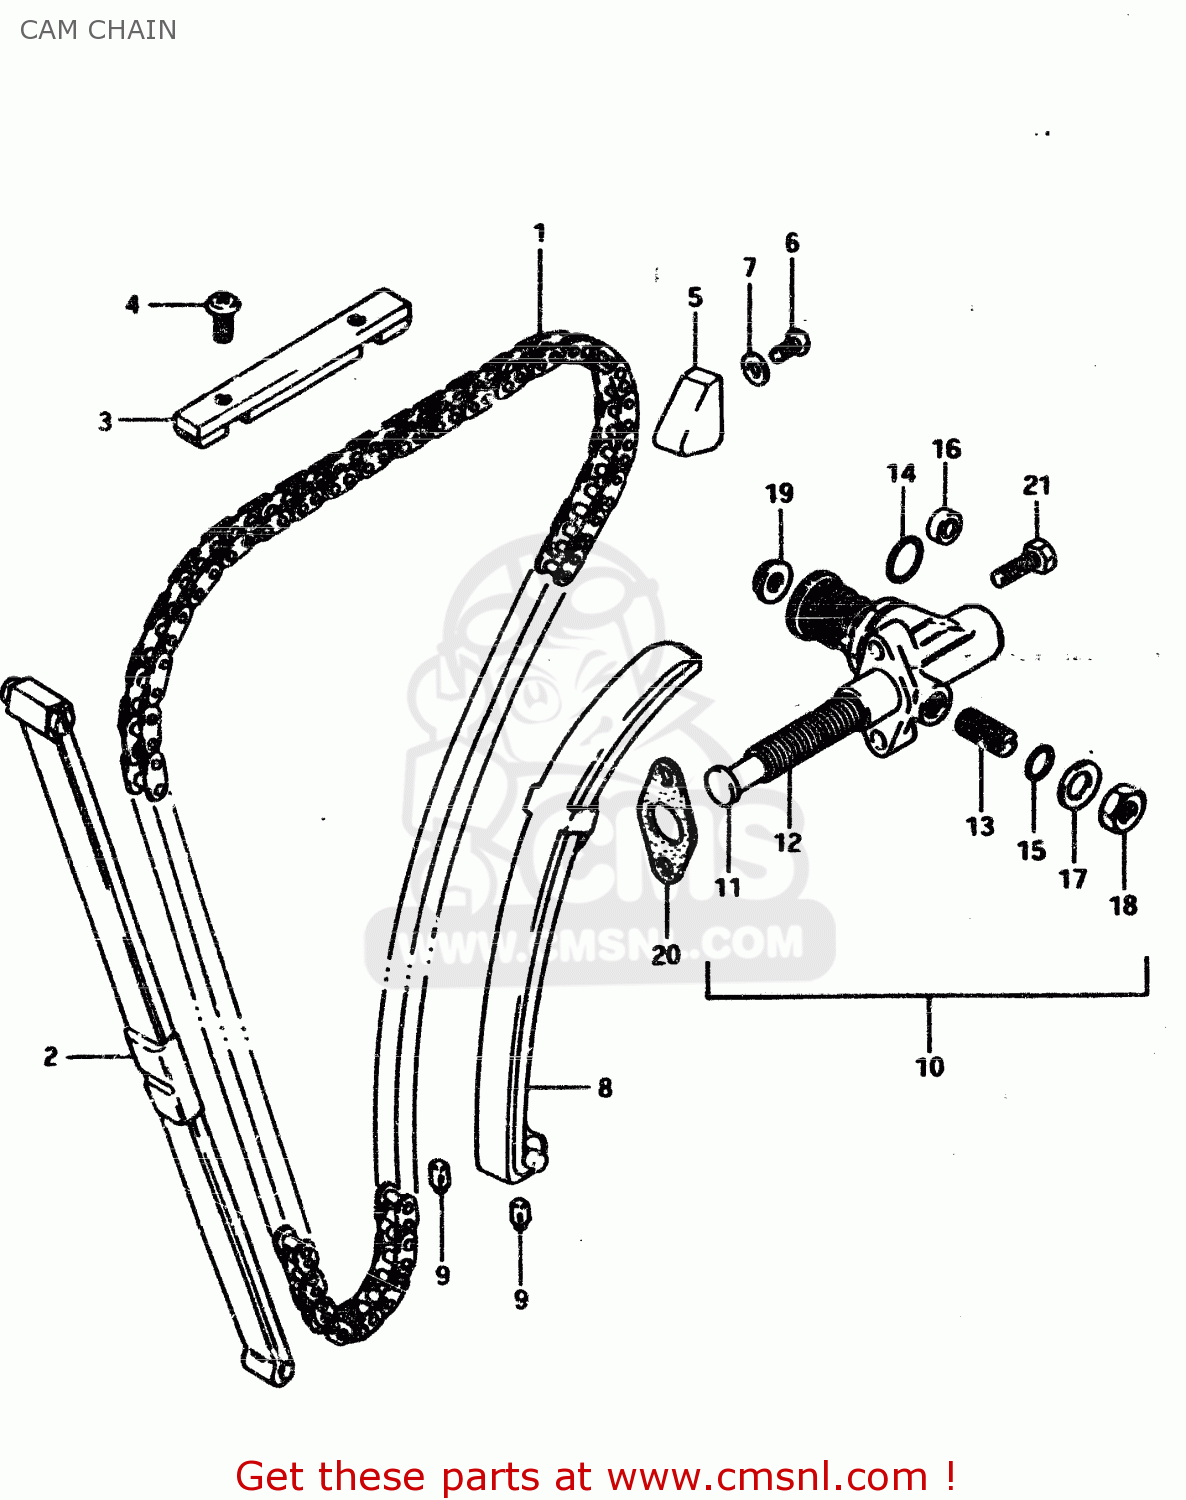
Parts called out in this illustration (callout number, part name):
1	CHAIN,CAMSHAFT DRIVE(120L)
2	GUIDE,CAM CHAIN NO.1
3	GUIDE,CAM CHAIN NO.3
4	SCREW
5	GUIDE,CAM CHAIN
6	BOLT 6X12
7	GASKET (NAS)
8	TENSIONER,CAM CHAIN
9	CUSHION,CAM CHAIN TENSIONER
10	ADJUSTER ASSEMBLY,TENSIONER
11	ROD,PUSH
12	SPRING
13	SCREW,TENSIONER ADJUST
14	O-RING
15	O-RING
16	OIL SEAL
17	WASHER,8.5X16X
18	NUT
19	NUT
20	GASKET,TENSIONER ADJUSTER (MCA)
21	SCREW
